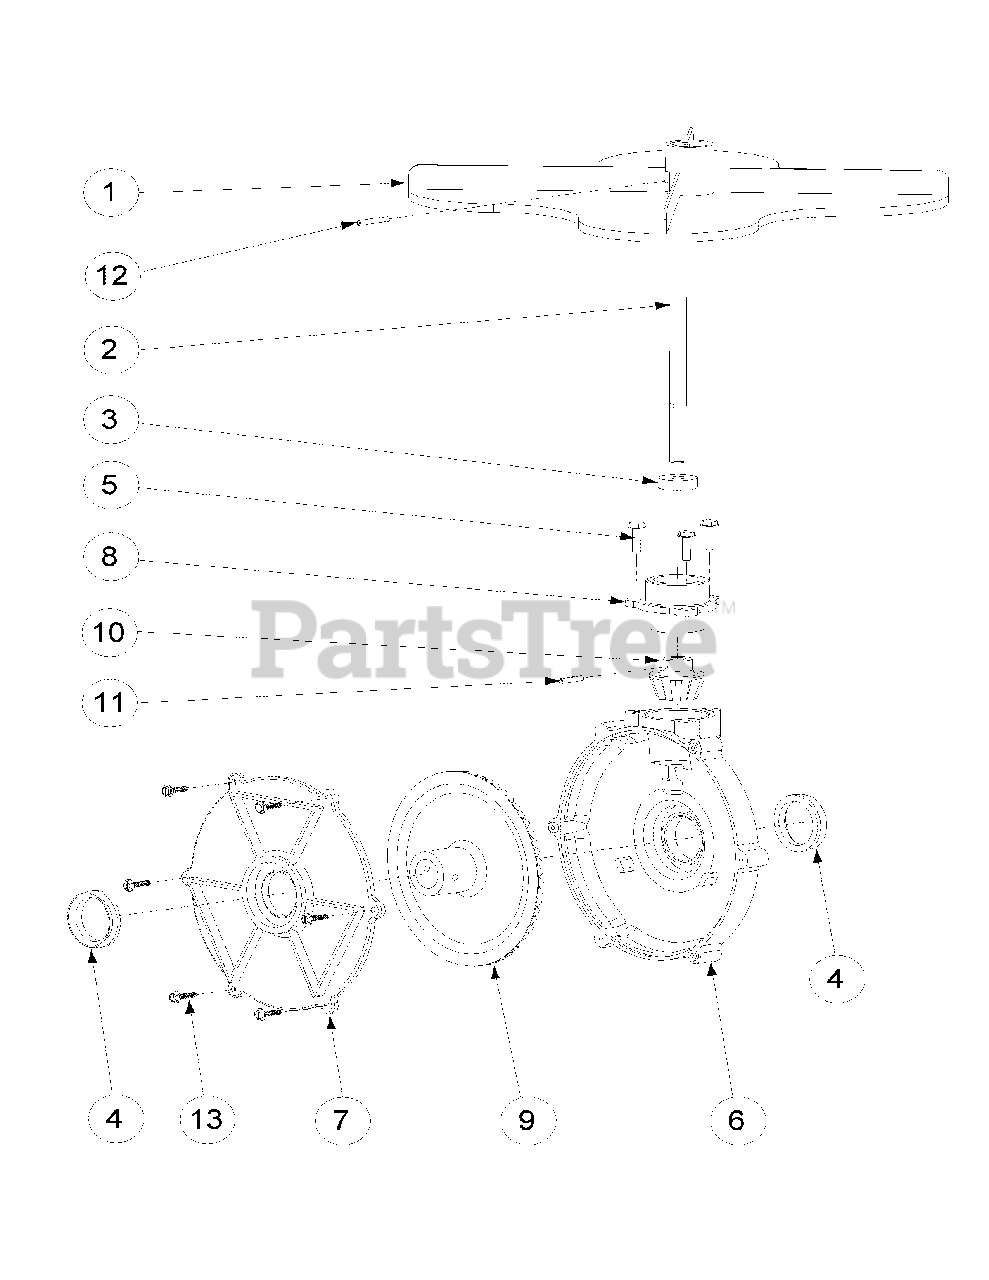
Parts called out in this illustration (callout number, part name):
2	Impeller Shaft
3	Oil Gearset Seal
4	V Gearset Seal
5	Tap Screw
6	Gearset Housing
7	Gearset Cover
8	Gearset Cap
9	Bevel Gearset Gear
10	Pinion Gearbox Gear
11	Roll Pin, 1/8 x 5/8
12	Roll Pin, 1/8 x 7/8, SS
13	Screw, 8-18, #6 x 5/8
